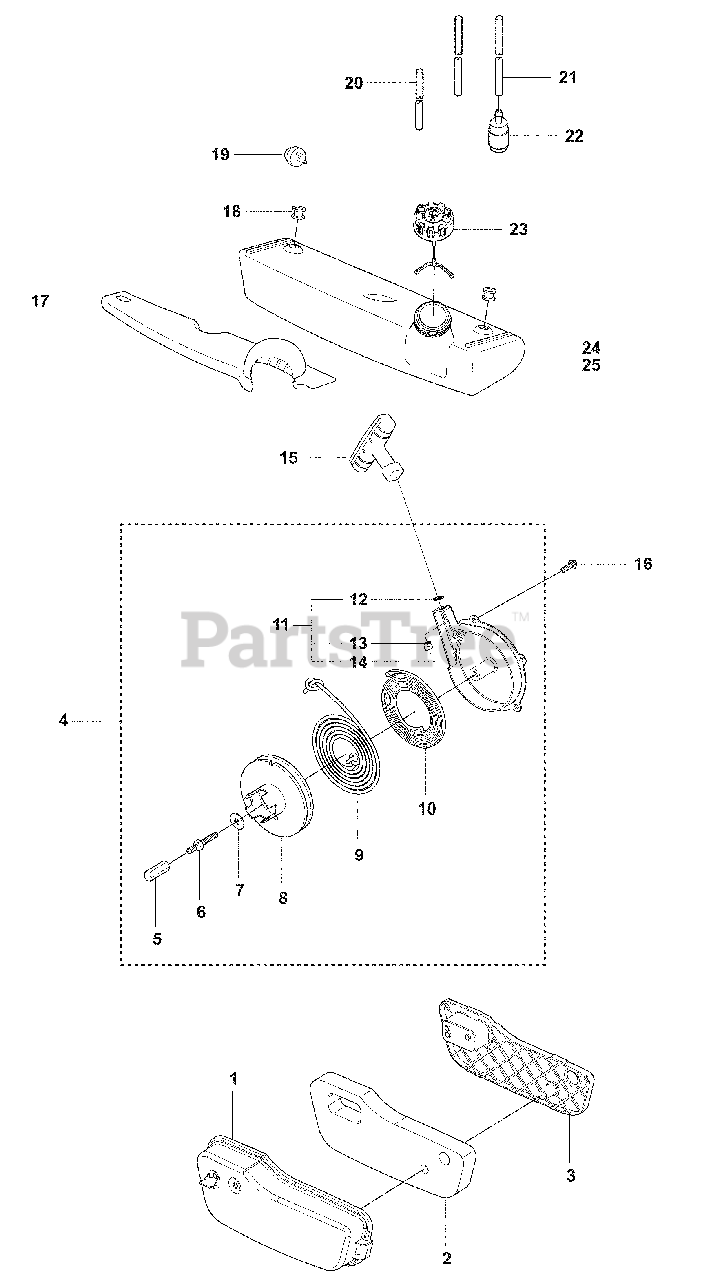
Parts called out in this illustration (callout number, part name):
2	Air Filter
3	NET AIR FILTER
4	STARTER DEVICE
8	STARTER PULLEY
9	Starter Rope
10	Recoil Starter Spring
12	Retaining Ring
13	SLEEVE, STARTER HOUSING
14	STARTER DEVICE
15	Starter Handle
18	Fuel Line Grommet
19	Air Purge Bulb
22	Fuel Filter Kit
23	Fuel Cap Assembly
